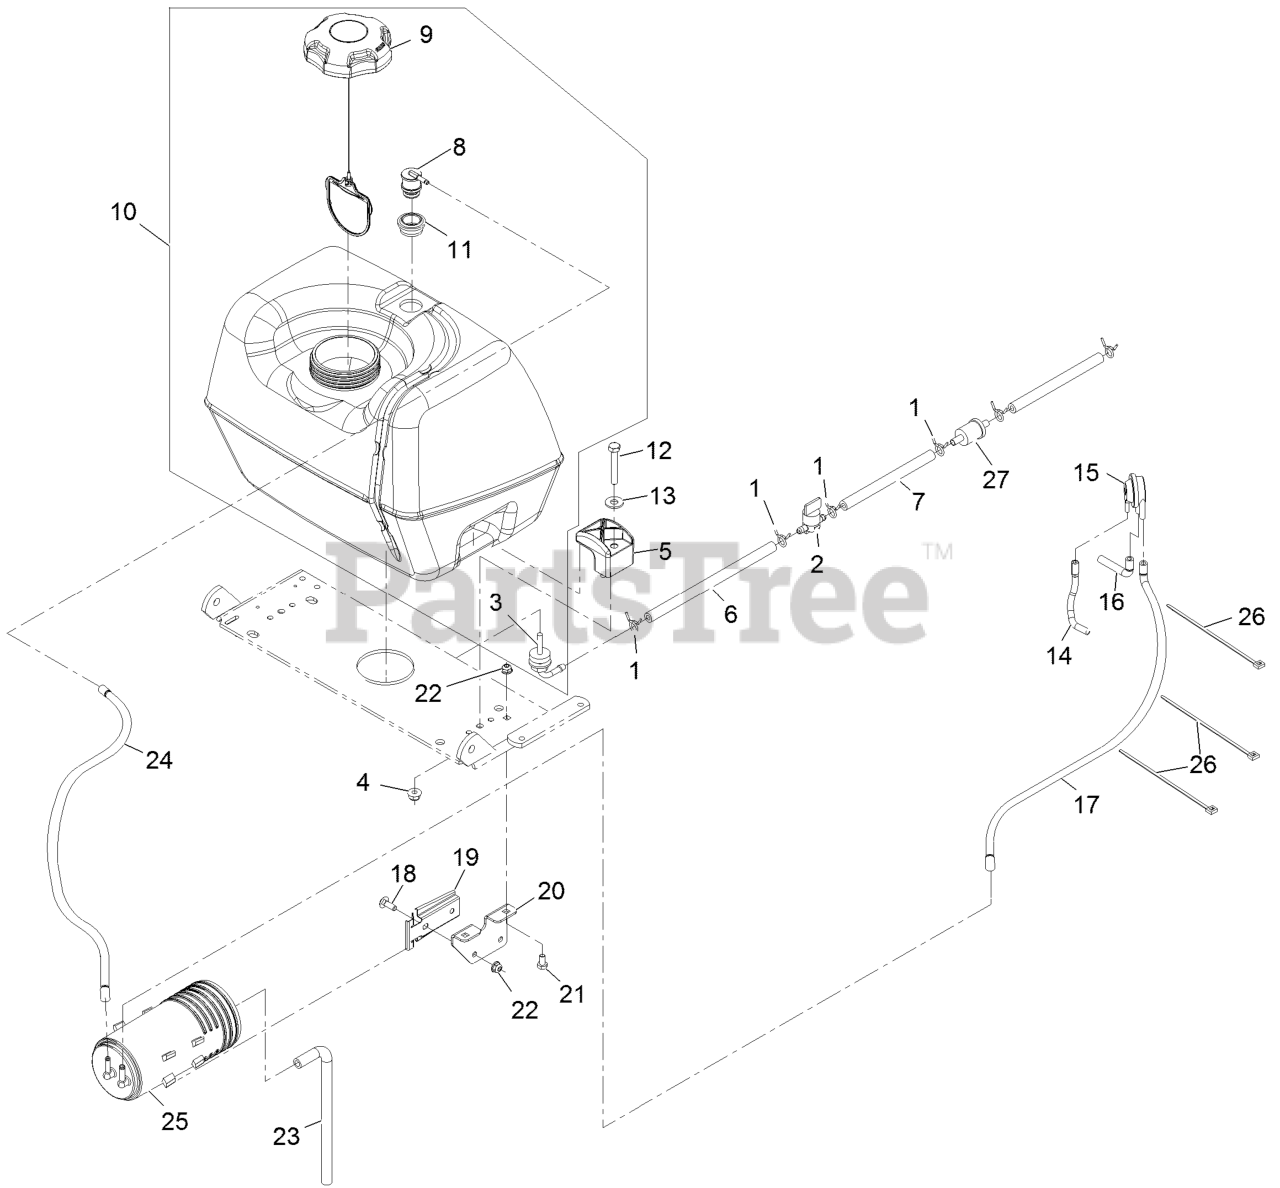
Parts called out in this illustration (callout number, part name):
1	CLAMP-HOSE
2	VALVE-FUEL
3	FITTING-FUEL, BULKHEAD
4	NUT-HF, NI
6	HOSE-FUEL
7	HOSE-FUEL
11	GROMMET
12	SCREW-HH
13	WASHER-FLAT
14	HOSE-VENT, FORMED
15	VALVE-CONTROL, VACUUM
16	HOSE-VENT, FORMED
17	HOSE-VENT, FORMED
18	SCREW-HH
19	BRACKET-CANISTER, CARBON
20	BRACKET-CANISTER, CARBON
21	BOLT-CARR
23	HOSE-VENT, CANISTER
24	HOSE-VENT
25	CANISTER-CARBON, 800CC
26	TIE-PLASTIC
27	Pn 49019-0014 Filter W/6in Fuel Line
